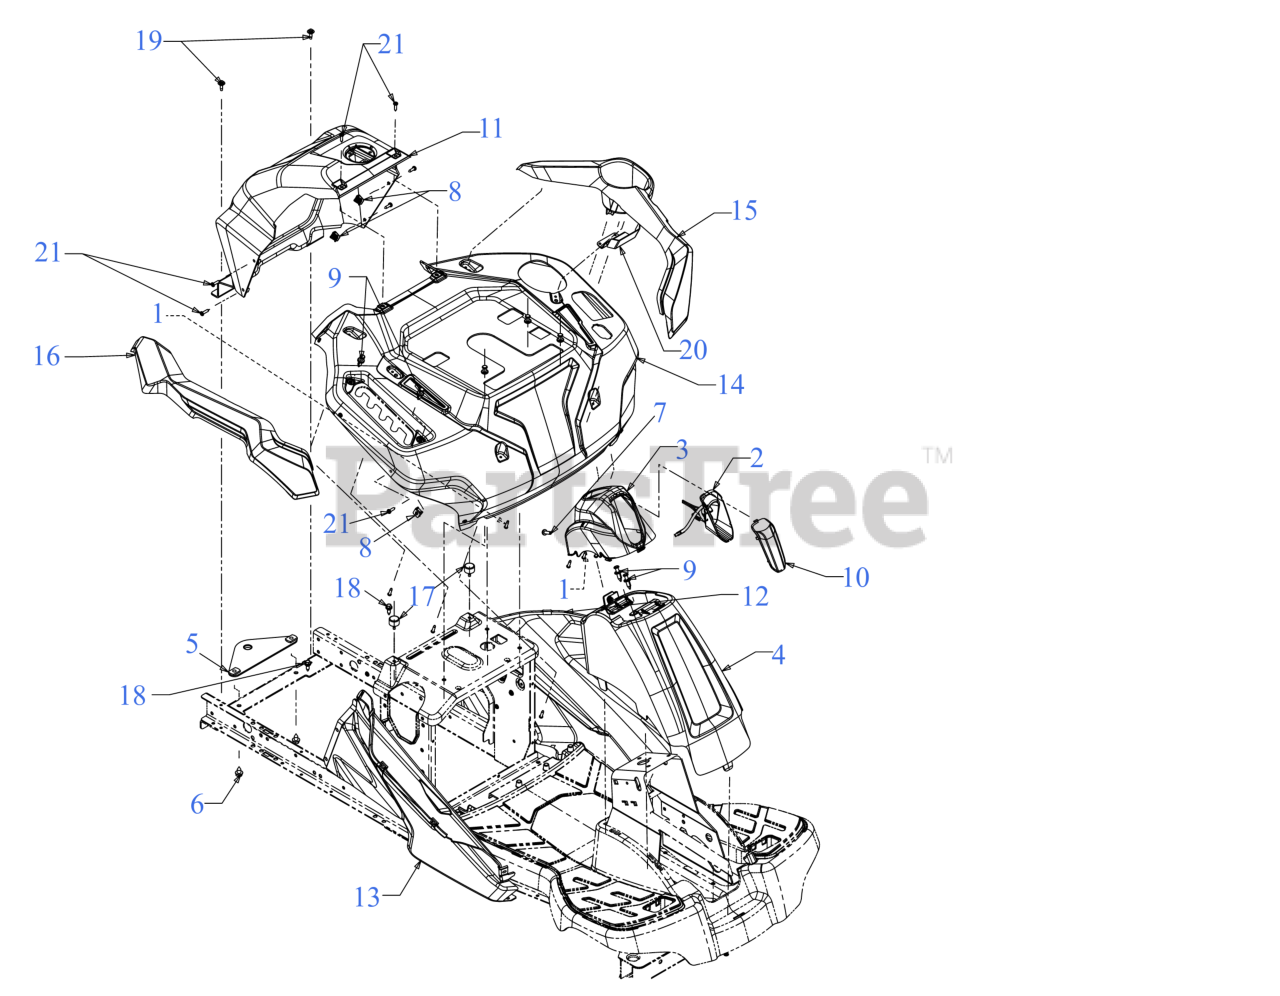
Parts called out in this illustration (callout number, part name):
1	SCREW, #8-16X.750 PH
2	LED HEADLIGHT HARNESS ASSEMBLY
3	COLUMN CAP (LIBERTY RED)
4	COLUMN COVER (LIBERTY RED)
6	SCREW 5/16-18 x .625
7	SCREW 1/4-20X.75
8	U-NUT #10-16
9	PLASTIC RIVET
10	LED HEADLIGHT LENS
11	REAR BODY COVER
12	BODY PANEL LH ECR12
13	BODY PANEL RH ECR12
14	FENDER
15	FENDER TRIM (LH) (LIBERTY RED)
16	FENDER TRIM (RH) (LIBERTY RED)
17	BUMPER .62 DIA x .50
18	SHOULDER SCREW
19	SHOULDER SCREW M6-1 .368 X.115
20	FENDER BRACKET
21	SCREW:10-6 x .75
